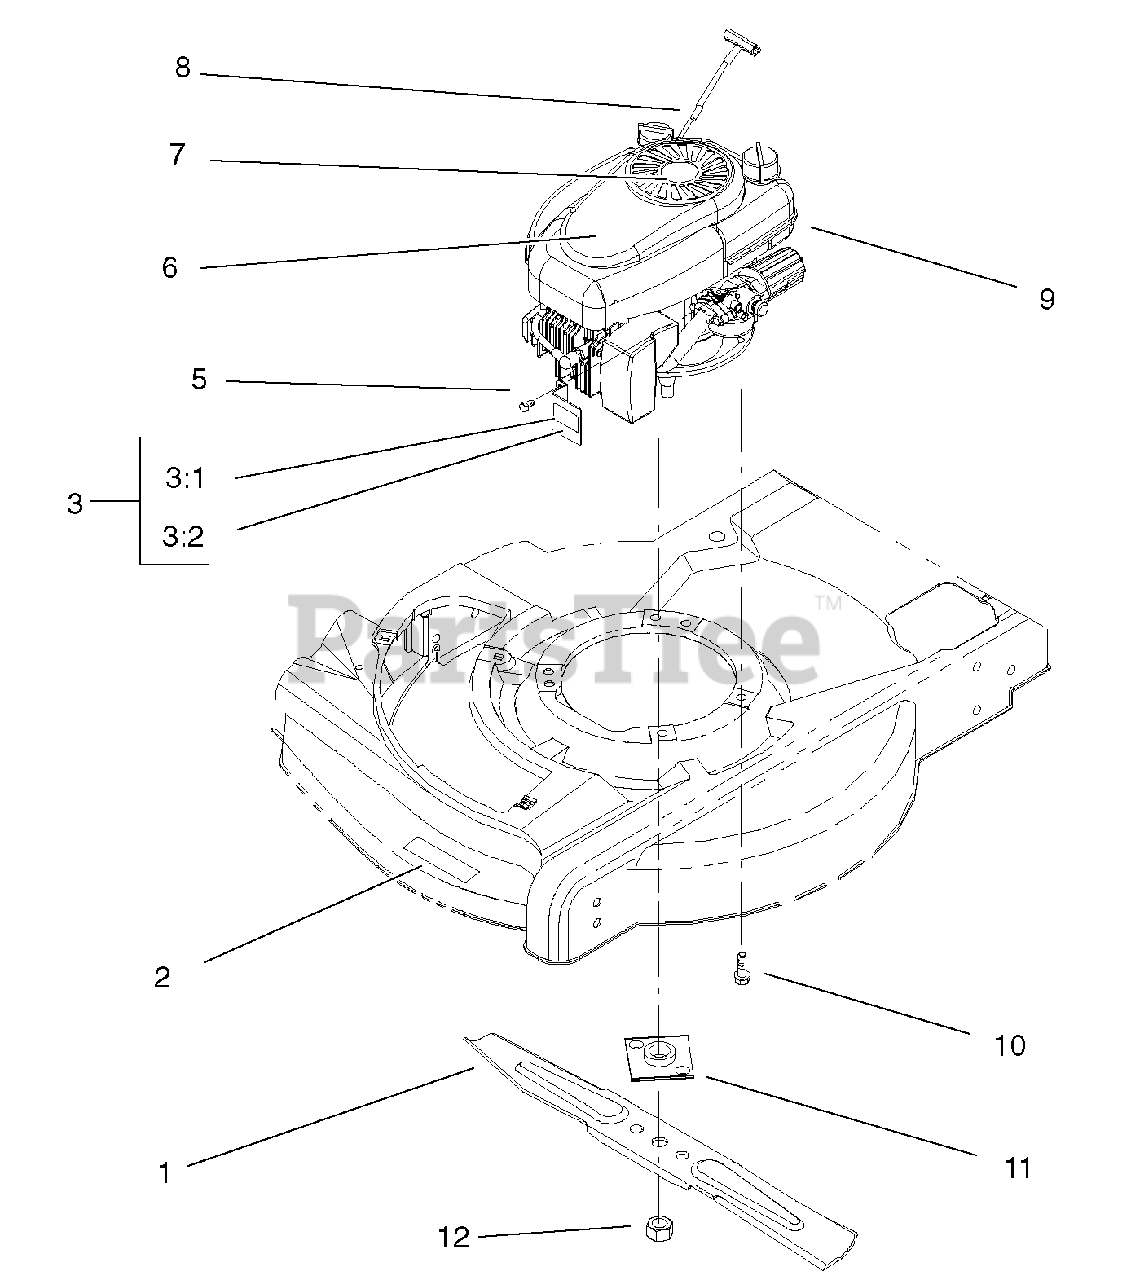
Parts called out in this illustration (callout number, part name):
2	Decal-Deck
3	Muffler Guard ASM
3:1	Decal-Surface, Hot
3:2	Guard-Muffler
6	Applique
7	Decal-Recoil, 5hp
8	Stop-Rope
10	Screw-Taptite W/Patch
11	Blade Retainer ASM
12	Nut-Blade
